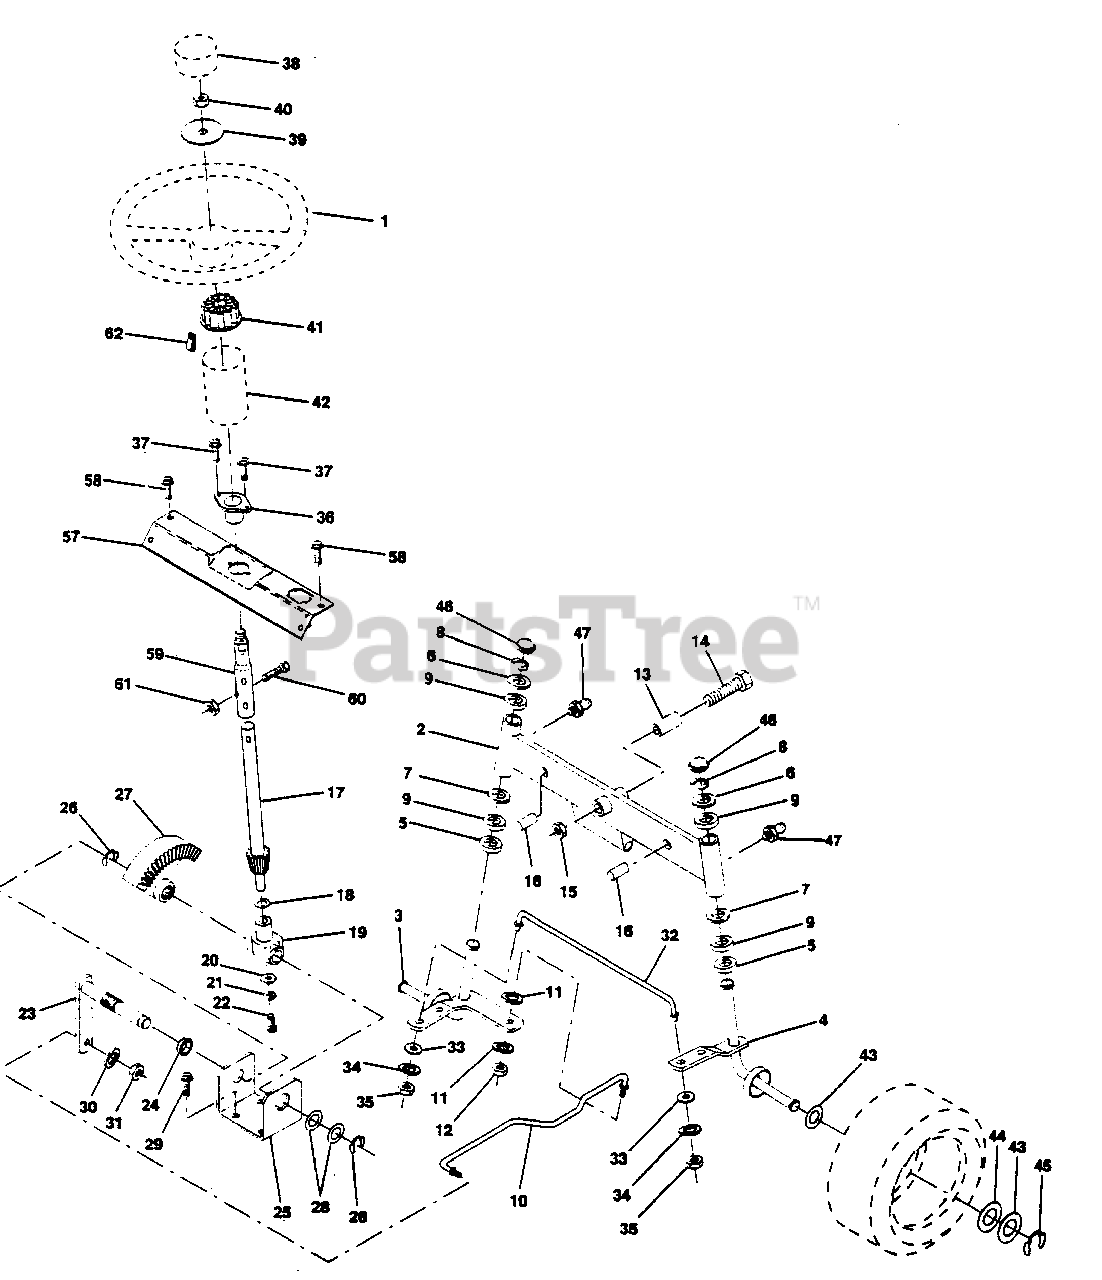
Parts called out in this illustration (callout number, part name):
1	Wheel Steering Auto Black (AYP part number)
2	Axle Asm Fr LT W/gzks 38/42 (AYP part number)
3	Spindle Asm LH (AYP part number)
4	Spindle Asm RH
5	Bearing Race Thrust Harden (AYP part number)
6	Washer 25/32 X 1-5/8 X 16ga (AYP part number)
7	Washer 27/32 X 1-1/4 X 16 Ga (AYP part number)
8	Ring Klip #t5304-75 (AYP part number)
9	Bearing Col Strg Blk (AYP part number)
10	Link Drag Sol Ball Jt 20 064 (AYP part number)
11	Washer Lock Hvy Hlcl Spr 3/8 (AYP part number)
12	Nut Fin Hex 3/8-24 Unf (AYP part number)
13	Spacer Bearing Axle Front (AYP part number)
14	Bolt Hex 5/8-11 Unc X 3-1/2 (AYP part number)
15	Nut Lock Flange 5/8-11 Unc (AYP part number)
16	Pin Axle 5/8 X 1 55/1 54 Lg (AYP part number)
17	Shaft Asm Strg Private Label (AYP part number)
18	Washer Thrust 515x 750x 033 (AYP part number)
19	Support Shaft (AYP part number)
20	Washer Shim 1/4 X 5/8 X 062 (AYP part number)
21	Washer Lock Hvy Helical 1/4 (AYP part number)
22	Screw Hex Socket 1/4-20 X 5/8 (AYP part number)
23	Shaft Asm Pittman (AYP part number)
24	Nyliner Snap In (AYP part number)
25	Bracket Steering (AYP part number)
26	Ring Klip #t5304-75 (AYP part number)
27	Gear Sector 22 Teeth (AYP part number)
28	Bearing Race Thrust Harden (AYP part number)
29	Screw Thdrol 3/8-16x3/4 Ty-tt (AYP part number)
30	Washer Lock Hvy Hlcl Spr 3/8 (AYP part number)
31	Nut Fin Hex 3/8-24 Unf (AYP part number)
32	Rod Tie Wire Form 19 75 Mech (AYP part number)
33	Bushing Link Drag Blk LR (AYP part number)
34	Washer 13/32 X 7/8 X 16ga (AYP part number)
35	Pin Cotter 1/8 X 3/4 Cad (AYP part number)
36	Bushing Strg (AYP part number)
37	Screw Slftp #10-16 X 1/2 Ty-b (AYP part number)
38	Insert Cap Strg Wh Au Gen Blk (AYP part number)
39	Washer 13/32 X 2-3/8 X 8 Ga (AYP part number)
40	Nut Lock Center 3/8-24unf (AYP part number)
41	Adaptor Wheel Strg 640/ 635id (AYP part number)
42	Boot Shaft Steering (AYP part number)
43	Washer 25/32 X 1 1/4 X 16 Ga (AYP part number)
44	Washer 25/32 X 1-5/8 X 16ga (AYP part number)
45	Ring Klip #t5304-75 (AYP part number)
46	Cap Spindle Fr Top Blk (AYP part number)
47	Fitting Grease (AYP part number)
57	Support Shaft Steering (AYP part number)
58	Screw Hex Wsh Thdrol 1/4-20 x 3/4 (AYP part number)
59	Shaft Extension Steering (AYP part number)
60	Bolt Fin Hex 5/16-18 unc x 1-1/4 (AYP part number)
61	Nut Lock Hex w/Insert 5/16-18 (AYP part number)
62	Clip Tinnerman (AYP part number)
